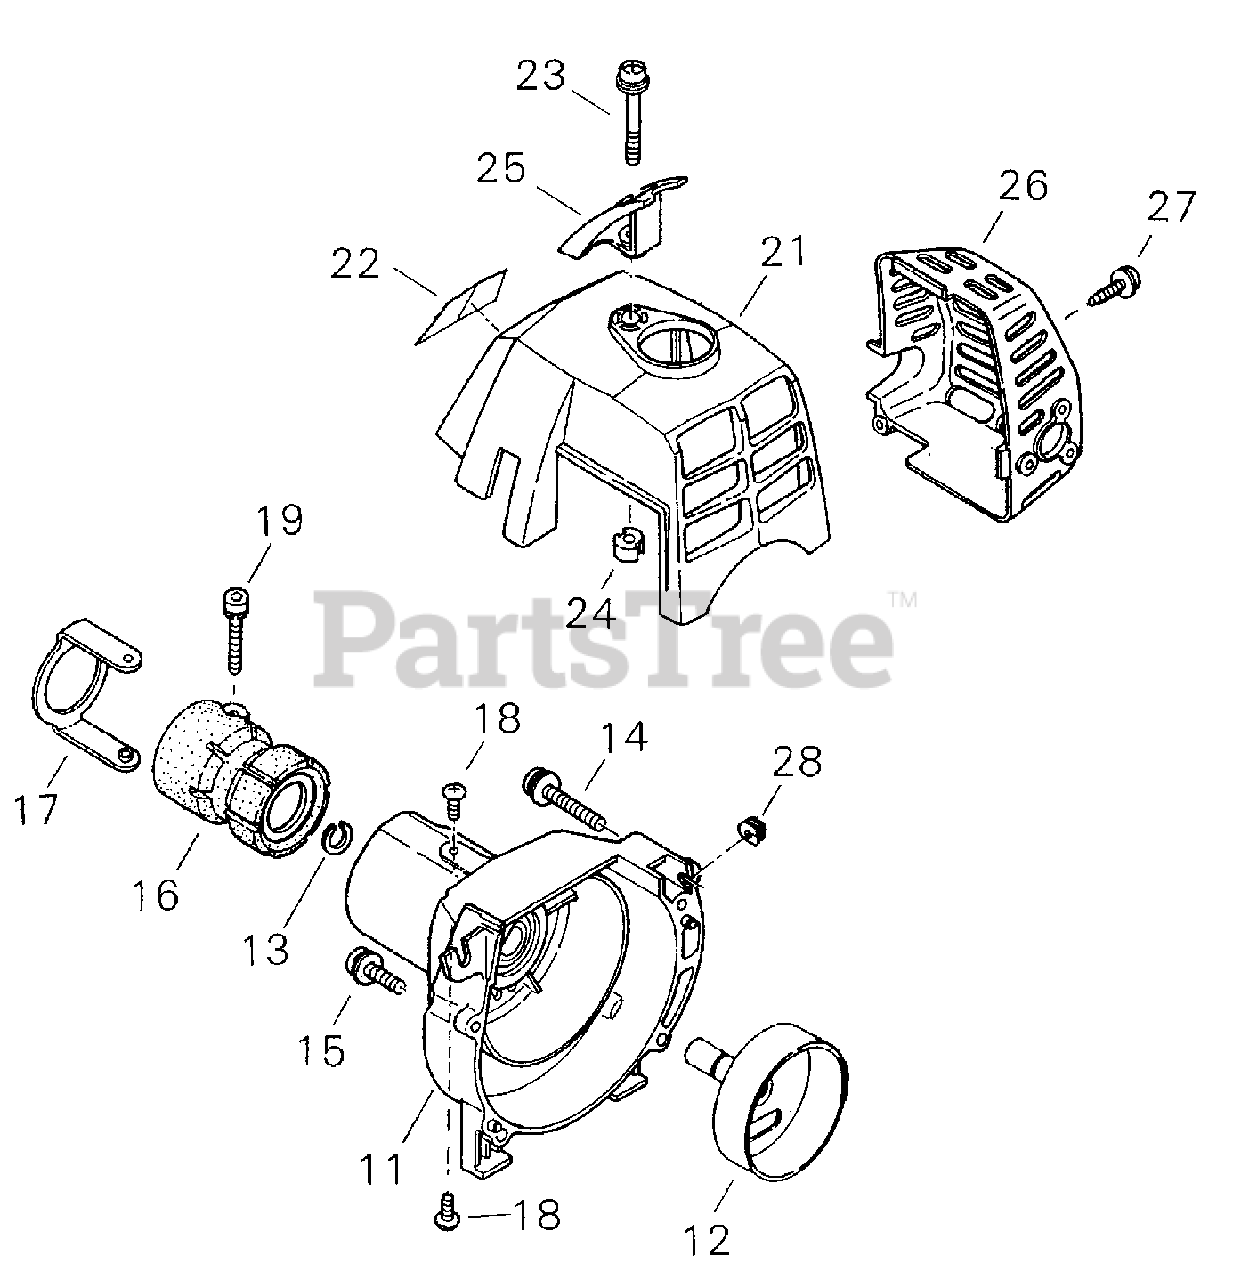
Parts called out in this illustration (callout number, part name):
3-11	COVER, FAN
12	DRUM, CLUTCH
13	RING, RETAINING
14	SCREW - 5X30
15	SCREW - 5X16
16	CUSHION
17	STOPPER
18	SCREW - 4X8
19	SCREW - 5X22
21	COVER, ENGINE
22	LABEL - MODEL
23	SCREW
24	INSULATOR
25	SPARK PLUG PROTECTOR
26	COVER, MUFFLER
27	SCREW
28	GROMMET
